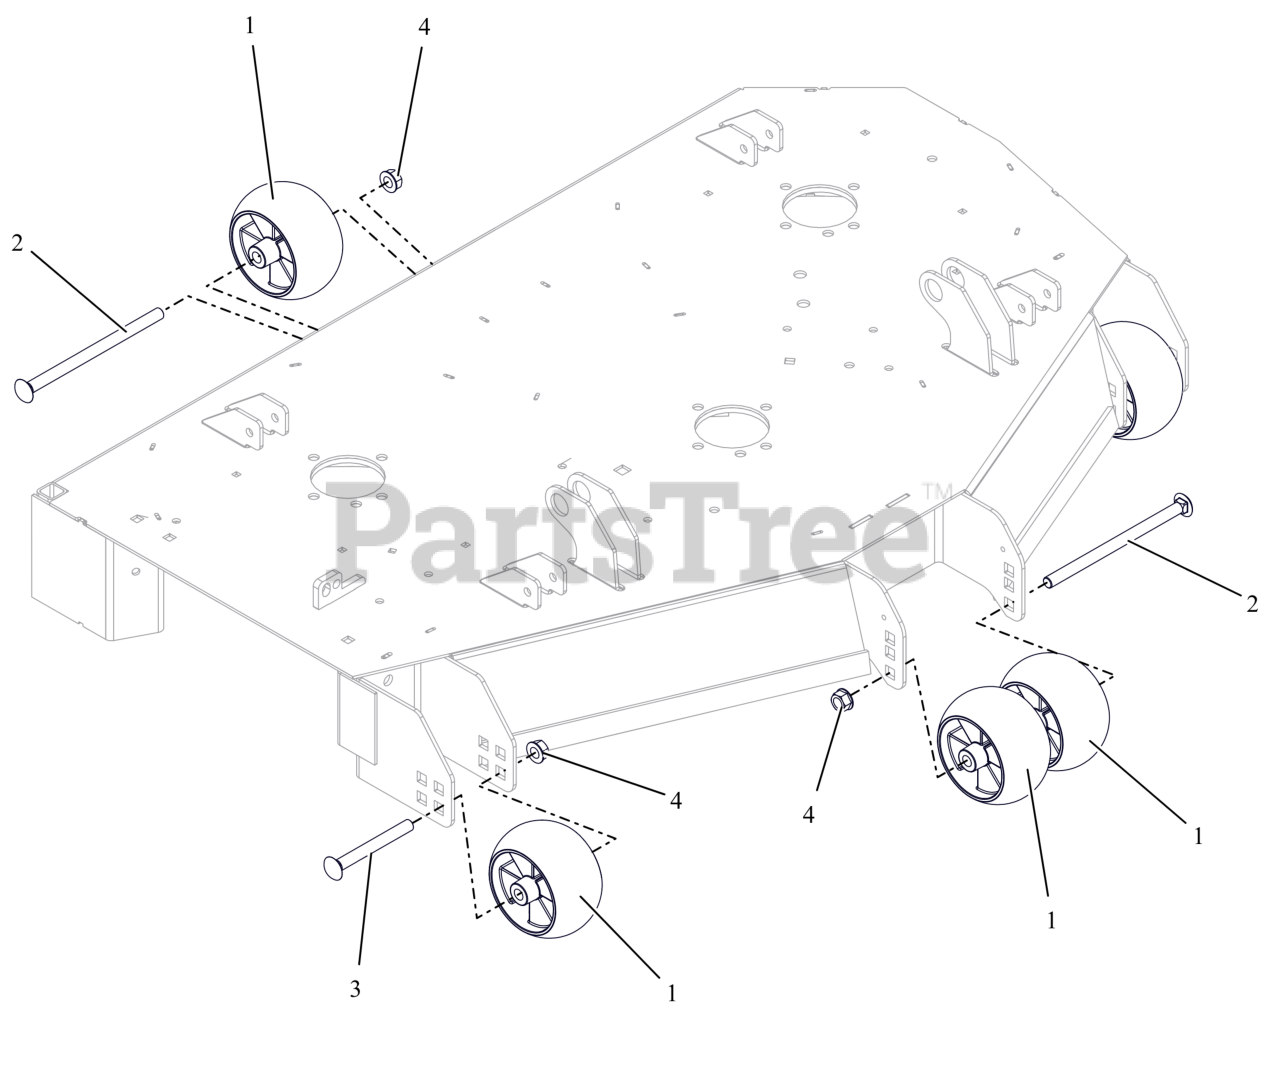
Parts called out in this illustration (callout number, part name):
1	WHEEL, ANTI SCALP - 5X3 CTR W/RIBS
2	BLT,RHSN .50-13X8.00 G5 ZCC NS
3	BLT,RHNS .50-13X4.50 G5 ZCC NS
4	NUT-LK-CTR-FLG .500-13 GG ZCC
